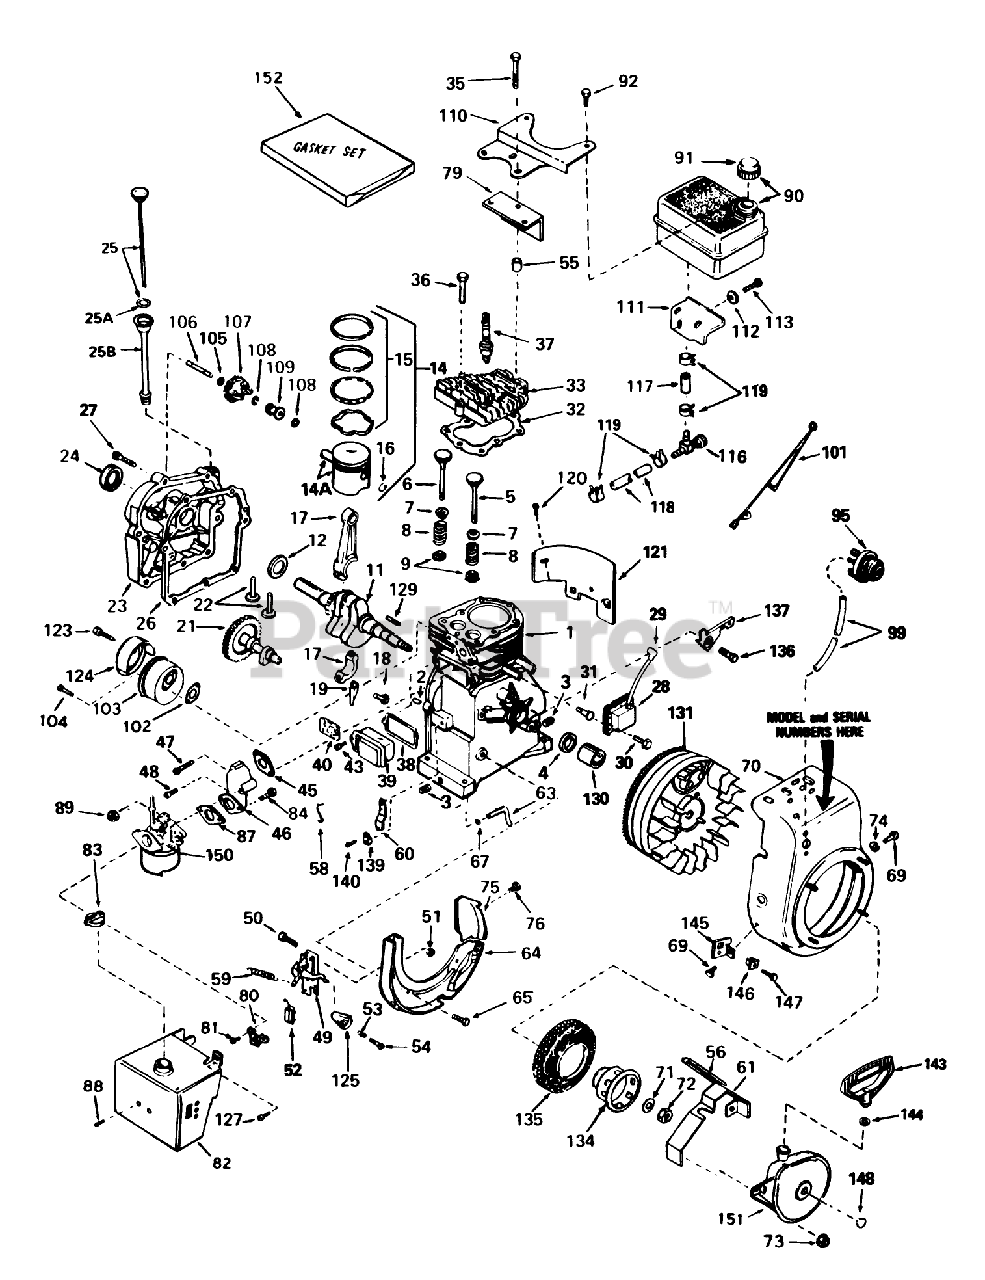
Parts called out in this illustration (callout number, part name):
1	Cylinder Assembly (Incl. Ref. #2, 3 35)
2	Pin-Dowel
3	Plug-Drain, Oil (SQH 1/4-18)
4	Seal-Oil
5	Valve, Intake (Std.) (Incl. Ref. #40)
5	Valve, Intake (1/32" oversize)(Incl. No. 40)
6	Valve, Exhaust (Std.)(Incl. No. 40)
6	Valve, Intake (1/32" oversize)(Incl. No. 40)
7	Cap-Upper Valve Spring
8	Spring-Valve
9	Cap-Valve, Spring
11	Crankshaft
12	Washer-Thrust
14	Piston-Pin Ring Assy. (Std.)(Incl. Ref. #14A, 15 16)
14	Piston-Pin Ring Assy. (.010 oversize)(Incl. Ref. #14A, 15 16)
14	Piston-Pin Ring Assy. (.020 oversize)(Incl. Ref. #14A, 15 16)
14A	Piston Pin Assy. (Std)(Incl. Ref. #16)
14A	Piston Pin Assy. (.010 oversize) (Incl. Ref. #16)
14A	Piston Pin Assy. (.020 oversize) (Incl. Ref. #16)
15	Piston Ring Set Std.
15	Piston Ring Set .010 O.S.
15	Piston Ring Set .020 O.S.
16	Ring-Retaining, Piston Pin
17	Rod Assembly, Connecting (Incl. Nos. 17 18)
18	Bolt-Rod, Connecting
19	Dipper-Oil
21	Camshaft (Compression Release)
22	Lifter-Valve
23	Cover, Cylinder (Incl. Ref. #24 106)
24	Seal-Oil
25	Dipstick
25A	O-Ring
25B	Tube Fill
26	Gasket-Cylinder Cover
27	Screw (1/4-20 x 1-1/4)
28	Solid State
29	Cover-Spark Plug
30	Screw
32	Gasket-Cylinder Head
33	CYLINDER HEAD
35	Screw (5/16-18 X 2)
36	Screw (5/16-18x1-1/2)
37	Plug, Spark (J17LM or equiv.)
37	Plug, Spark (Champion RCJ-8)
38	Gasket Breather
39	Breather Assembly (Incl. Nos. 52 84)
40	Element-Breather
43	Screw
45	Gasket-Intake
46	Pipe-Intake (Incl. Ref. #47)
47	Screw-Hex Hd.
48	Screw (1/4-20 x 1-19/32)
49	Control Assembly, Speed (Incl. Ref. #155 thru 158 160)
50	Screw
51	Nut-Lock
52	Terminal
53	Spring-Compression
54	Screw
55	pacer
56	Seal, Snowguard
58	Jet-Main
59	Spring-Extension
60	Lever-Governor
61	Guard-Starter
63	Rod-Governor
64	Baffle-Blower Housing
65	Screw (1/4-20x19/32)
67	Washer-Flat
69	Screw
70	Housing-Blower
71	Washer-Belleville
72	Nut-Flywheel
73	Nut and Lock Washer (1/4-28)
74	Washer
75	Baffle-Extension
76	Screw-Hex Washer Hd.
79	Baffle-Heat
80	Bracket-Choke
81	Screw (10-32 x 1/2)
82	Cover-Carburetor
83	Knob-Control
87	Gasket
88	Screw (8-32 X 5/16)
89	Nut and Lock Washer (1/4-28)
90	481-1261 SENATOR TI
91	Cap, Fuel
92	Screw (1/4-15x7/8)
95	Primer Assy.
99	Line-Primer
101	Ground Wire
102	Gasket Exhaust
103	Muffler
104	Screw
105	Washer-Flat
106	Shaft-Governor
107	Governor Gear ASM
108	Ring-Retaining
109	Spool-Governor
110	Plate-Fuel Tank
111	Bracket-Fuel Tank
112	Washer
113	Screw Assembly
116	Valve-Shut Off
117	Line-Fuel (8.62)
118	Line-Fuel
119	Clamp-Line, Fuel
120	Screw
121	Extension-Blower
123	Screw (1/4-15x7/8)
124	Cover-Muffler
125	Knob-Control
127	Screw (10-32x1/2)
129	Key-Flywheel
130	Spacer
131	CLAMP
134	Cup-Starter
135	Screen-Starter
136	Screw (10-24 x 9/16)
137	Bracket-Hold Down
139	Clamp-Lever, Governor
140	Screw
143	Handle-Starter, Mitten Grip
144	Washer
145	Bracket
146	Grommet
147	Screw
148	Plug-Starter
150	Carburetor (Incl. Ref. #87)
151	Starter-Rewind
152	Gasket Set (Incl. items marked*
